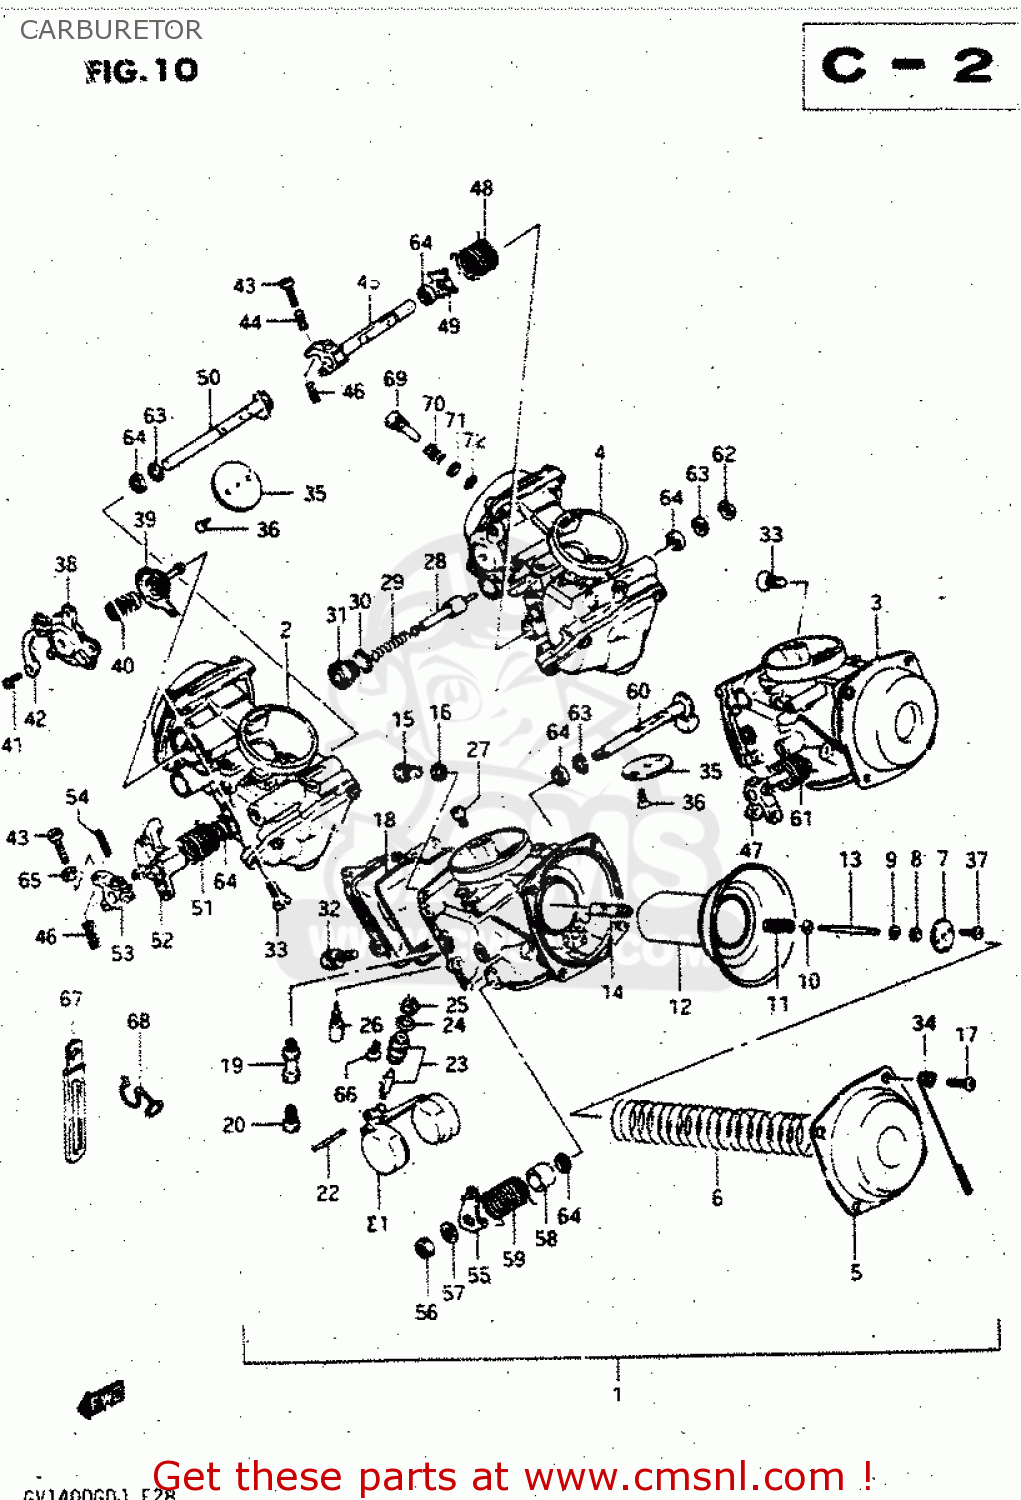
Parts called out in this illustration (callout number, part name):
1	CARBURETOR ASSY, FRONT LH
2	CARBURETOR ASSY, FRONT RH
3	CARBURETOR ASSY, REAR LH
4	CARBURETOR ASSY, REAR RH
5	COVER,DIAPHRAGM
6	SPRING,DIAPHRAGM
7	PLATE
8	RING
9	CLIP,NEEDLE
10	WASHER
11	SPRING
12	DIAPHRAGM,CARBURETOR
13	NEEDLE, JET (5D20-3)
14	JET, NEEDLE (Y-8)
15	SCREW
16	WASHER,NEEDLE NOZZLE
17	SCREW
18	O RING,FLOAT CHAMBER
19	HOLDER,MAIN JET
20	JET,MAIN(105)
21	FLOAT
22	PIN,FLOAT
23	VALVE ASSEMBLY,NEEDLE
24	O-RING,NEEDLE VALVE
25	FILTER
26	JET,PILOT(25)
27	JET,ENRICH
28	PLUNGER
29	SPRING,STARTER PLUNGER
30	O RING
31	HOLDER,GUIDE
32	SCREW
33	SCREW
34	CLIP
35	VALVE,THROTTLE
36	SCREW
37	SCREW
38	COVER
39	DIAPHRAGM ASSY
40	SPRING
41	SCREW
42	BRACKET
43	SCREW
44	SPRING
45	SHAFT,THROTTLE
46	SPRING,THROTTLE SCREW
47	SHAFT,THROTTLE
48	SPRING,THROTTLE VALVE
49	PLATE
50	SHAFT,THROTTLE
51	SPRING
52	LEVER,THROTTLE
53	LEVER,THROTTLE
54	PIN,THROTTLE SHAFT
55	LEVER,THROTTLE
56	NUT 8MM
57	WASHER
58	RING
59	SPRING
60	SHAFT,THROTTLE
61	SPRING,THROTTLE VALVE
62	E RING
63	GASKET,THROTTLE SHAFT (NAS)
64	SEAL,THROTTLE SHAFT
65	NUT
66	SCREW
67	CLAMP
68	CLAMP
69	SCREW,PILOT
70	SPRING
71	WASHER
72	O RING,PILOT AIR SCREW
